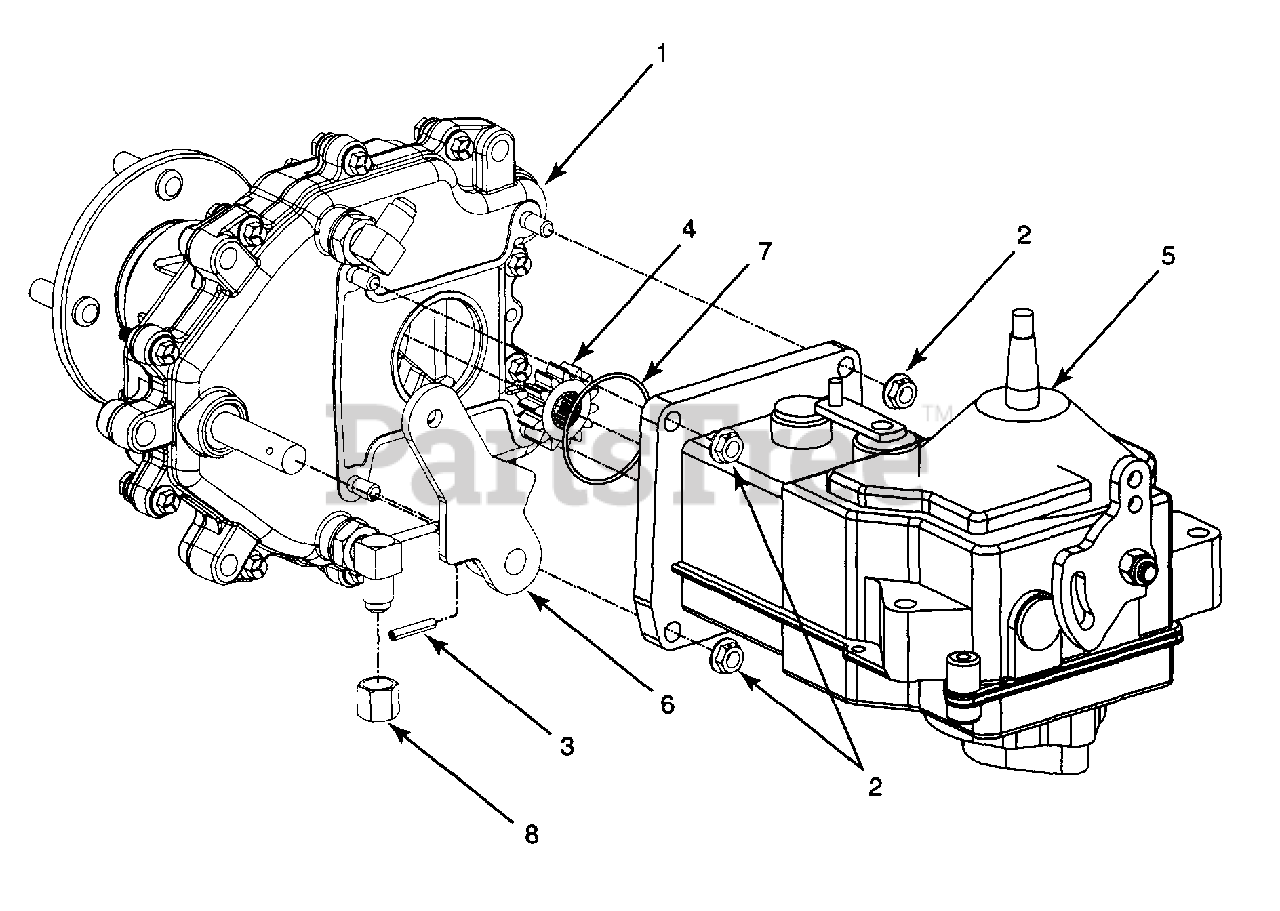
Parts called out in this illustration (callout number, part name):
1	Drive Ass'y, Complete Final
2	Nut, Hex Flange Lock, 5/16-18 GR5
3	Pin, Spirol, 3/16 x 1.0 HD
4	Gear, Spur, 14T
5	Transmission, Hydro: BDR
6	Lever, Park Brake
7	O-Ring, 2.0 Dia
8	Nut, Cap, 3/8
